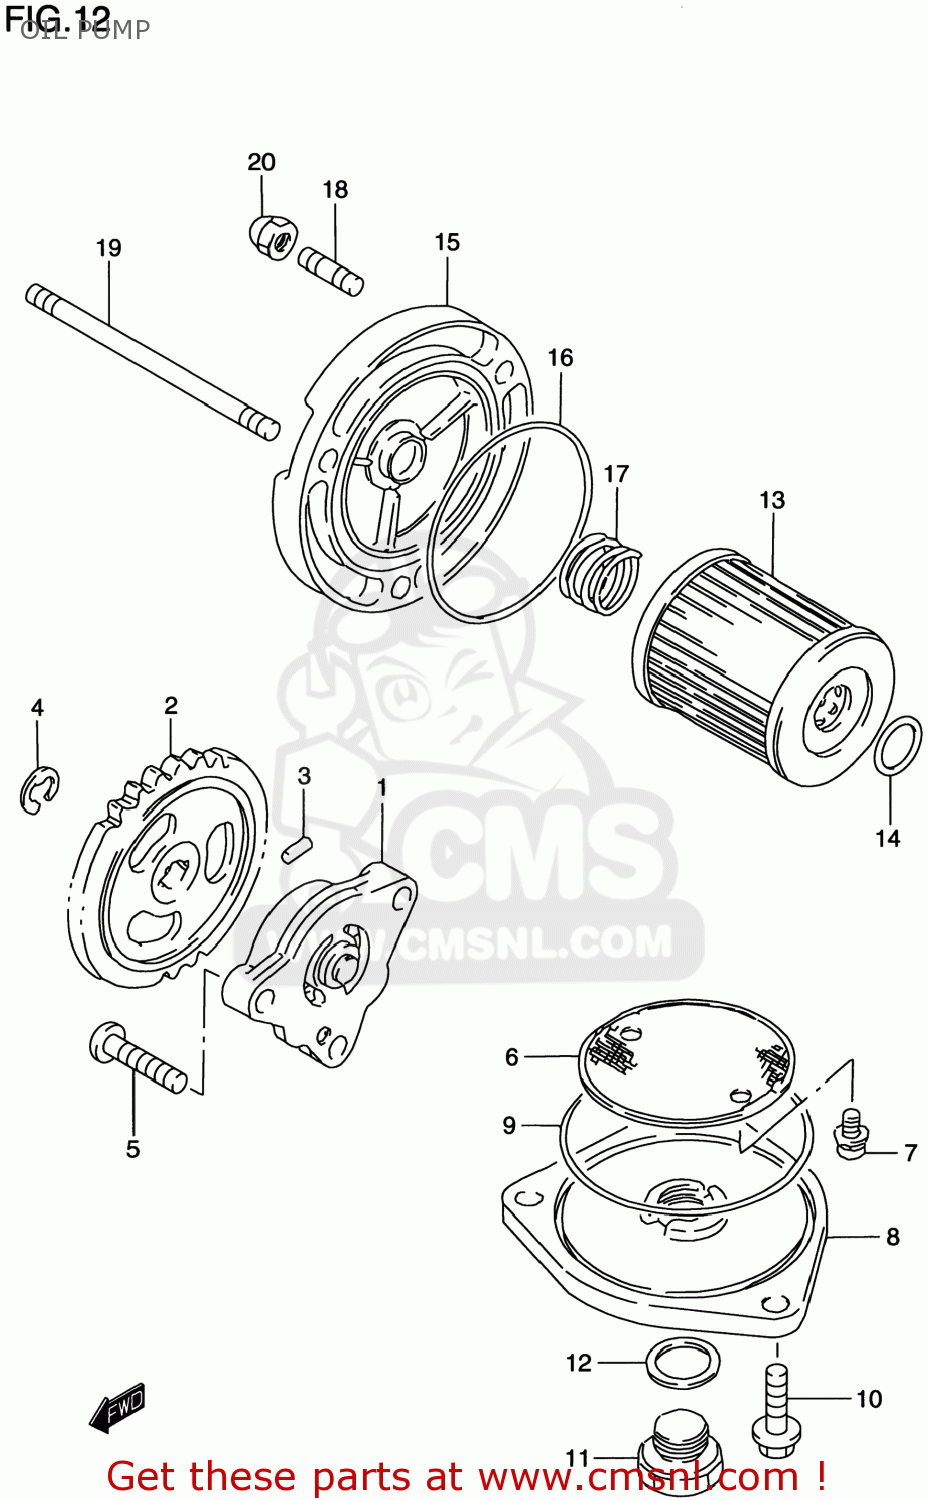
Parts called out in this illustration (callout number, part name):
1	PUMP ASSY,ENGINE OIL
2	GEAR,OIL PUMP DRIVEN (N
3	PIN(2.5X11.8)
4	E.RING
5	SCREW
6	STRAINER,ENGINE OIL
7	SCREW
8	CAP,OIL STRAINER
9	O RING(D:2.4,ID:60.5)
10	SCREW
11	PLUG(14X12)
12	GASKET(13.8X18.8X4.8) (NAS)
13	FILTER,OIL
14	O RING(D:1.9,ID:13)
15	CAP,OIL FILTER
16	O RING(D:2.4,ID:52.6)
17	SPRING
18	STUD 6X12
19	BOLT,STUD
20	NUT
